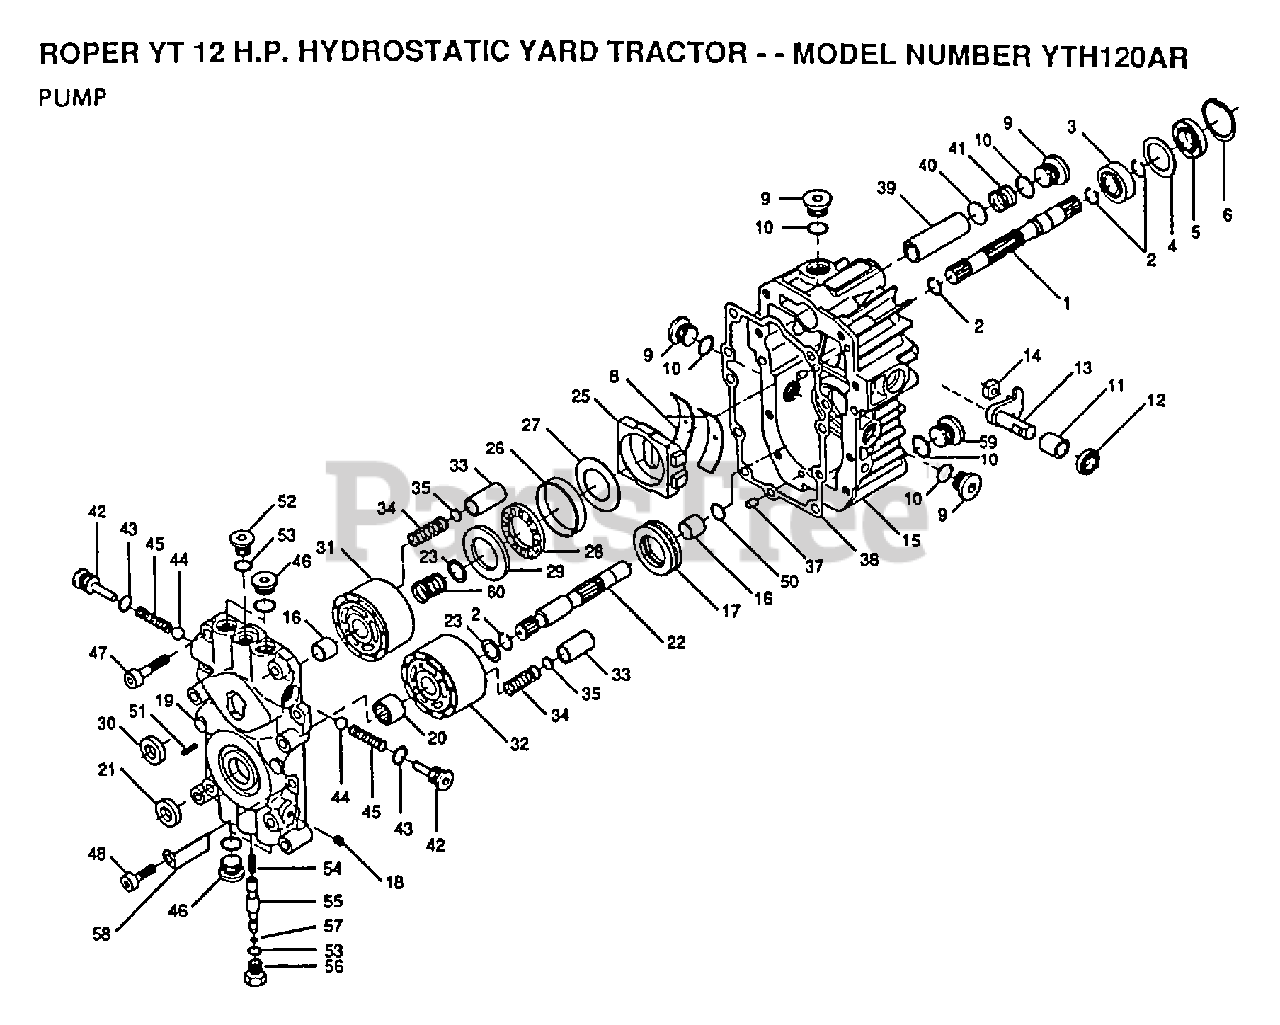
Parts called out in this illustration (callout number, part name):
1	SHAFT.PU.2003022
2	RETAINIANG RING-(2003016)
3	BALL BEARING
4	SPACER
5	SEAL LIP
6	RING.RET.2003052
8	CRADLE BEARING (2003023)
11	BEARING
12	SEAL.9008000-0126
13	TRUNION ARM (2003005)
14	GUIDE.2000015.HYD
16	JOURNAL BRG(2003071)
19	CENTER SECTION
20	NEEDLE BEARING
21	LIP SEAL-9008000-0127
22	SHAFT
23	WASHER
30	SEAL LIP
31	CYLINDER BLOCK
32	CYLINDER BLOCK(70331)
34	PISTON SPRING
35	WASHER.TR.2003019
37	PIN
38	GASKET.20030600
39	FILTER
40	WASHER (2000011)
41	SPRING
45	SPRING.2003012.HY
46	PLUG
47	SCREW9007314-0808
50	WASHER
51	PIN
52	PLUG
53	O RING
56	BYPAS KT 25130011
57	O RING (9004175-0027)
58	ADHESIVE LABEL
59	PLUG
